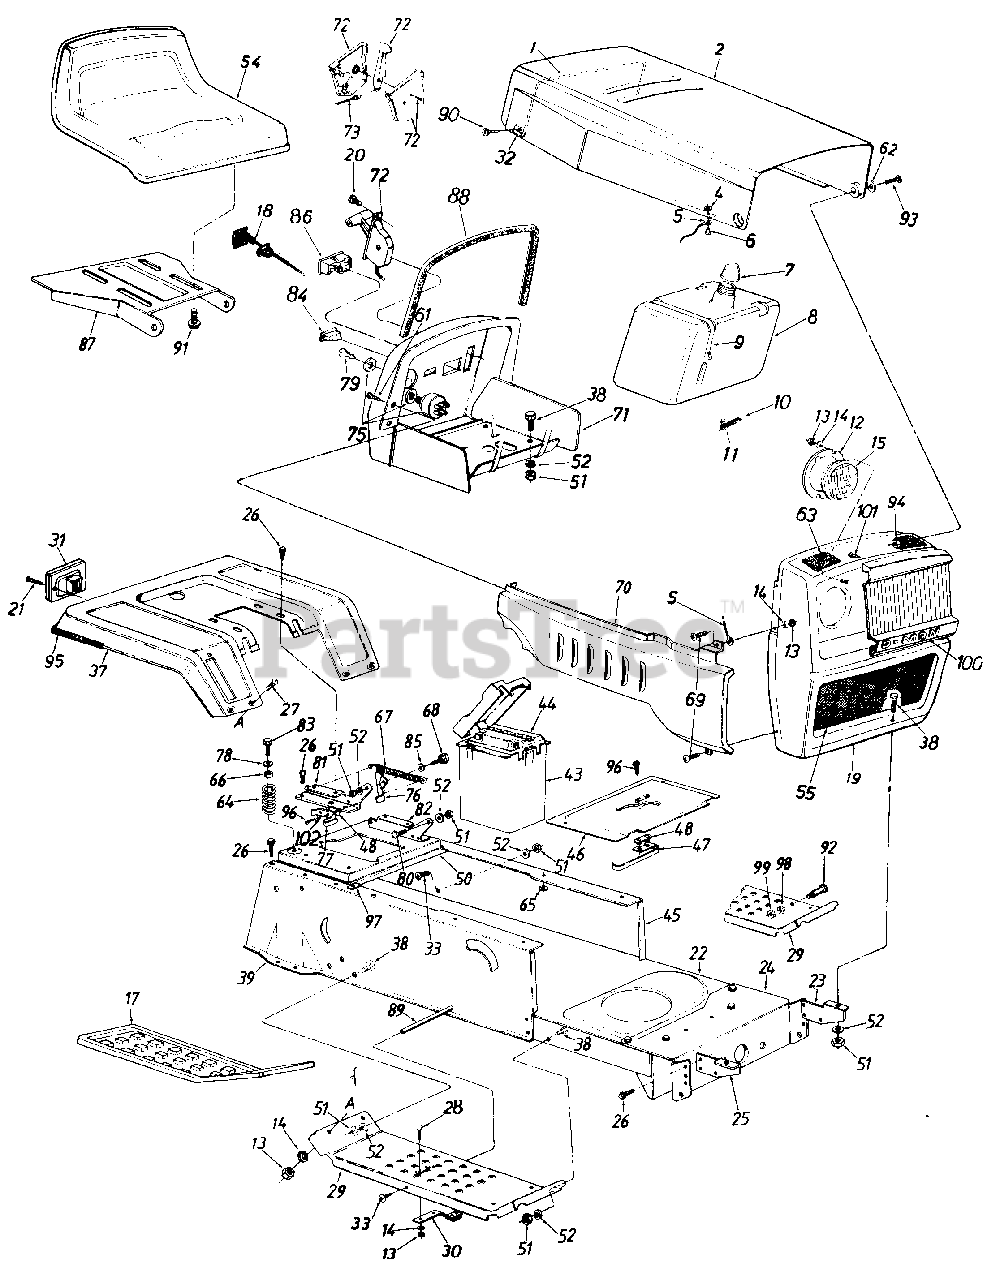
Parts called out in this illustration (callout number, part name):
1	Hood Spring
5	Hood Stop 7" Lg.
6	Pop Rivet
7	Fuel Cap Gauge
8	Fuel Tank
9	Tie Strap
10	Fuel Line
11	Hose Clamp
12	Headlight Retainer
13	Hex Nut 1/4-20 Thd.
14	L-Wash. 1/4" I.D.
15	Headlight
17	Foot Pad L.H.
18	Choke Control 29" Lg.
21	Truss AB-Tap Scr. #6 x .62" Lg.
22	Lower Frame
23	Grille Mount Brkt.
24	Front Pivot Brkt.
25	Grille Mount Brkt.
26	Hex Wash. Hd. AB-Tap Scr. 5/16 x .75" Lg.
27	Carriage Bolt 1/4-20 x 2.0"
28	Carriage Bolt 1/4-20 x .62"
29	Running Board
30	Blade Brake Ass'y.
31	Taillight
32	Hood Spring Retainer
33	Truss Mach. Scr. 5/16-18 x .75" Lg.
37	Fender
38	Hex Bolt 5/16-18 x .75" Lg.
39	R.H. Side Frame
43	Battery Box w/Cover
44	12-V Battery
45	L.H. Side Frame
46	Shift Cover
47	Reverse Safety Switch
48	Insulator Nut Plate
50	Hitch Plate
51	Hex Nut 5/16-18 Thd.
52	L-Wash. 5/16" I.D.
54	Seat Ass'y.
55	Grille Insert
61	Truss Mach. Tap Scr. #10 x .50" Lg
62	Washer :39a I.D. x .62" O.D.
63	Foam Strip 3/8 x 1-1/8 x 1-1/2
64	Compression Spring
65	Ext. L-Wash. 5/16" I.D.
66	Bushing
67	Ext. Spring 5.31" Lg.
68	Shld. Bolt .437" Dia. x .268"
69	Truss Hd. Scr. 1/4-20 x .75"
70	R.H. Grille Side Panel
71	Dash Panel Ass'y.
72	Throttle Control Box Ass'y.
73	Throttle Control Wire
75	Ignition Switch
76	Seat Lift Bracket
77	Spring Switch
78	Fl-Wash. .344" I.D.
79	Ignition Key
80	Shld. Bolt .437" Dia. x .162"
81	Seat Pivot Brkt. Support R.H.
82	Seat Pivot Brkt. Support L.H.
83	Hex Hd. Tap Scr. 5/16-18 x 1" Lg.
84	Light Switch
85	Spr-Wash. .445" I.D. x .75" O.D.
86	Ammeter
87	Seat Pivot Bracket
88	Molding Strip 27" Lg.
89	Running Board Rod
90	Self-Tap Scr. .5" Lg.
91	Hex Wash. Hd. Tap Scr. 3/8-16 x .75" Lg.
92	Shld. Bolt .50" Dia. x 34"
93	Shld. Bolt .375 Dia. x .125
94	Hex L-Nut 1/4-28 Thd.
95	Trim Strip 81"
96	Hex Wash. Hd. AB-Tap Scr. #8 x .50" Lg.
97	Speed Nut #10Z
98	L-Wash. 3/8" I.D.
99	Hex Nut 3/8-16 Thd.
100	Bezel
101	Self-Tap Scr. #8 x .5" Lg.
102	Fiber Washer
